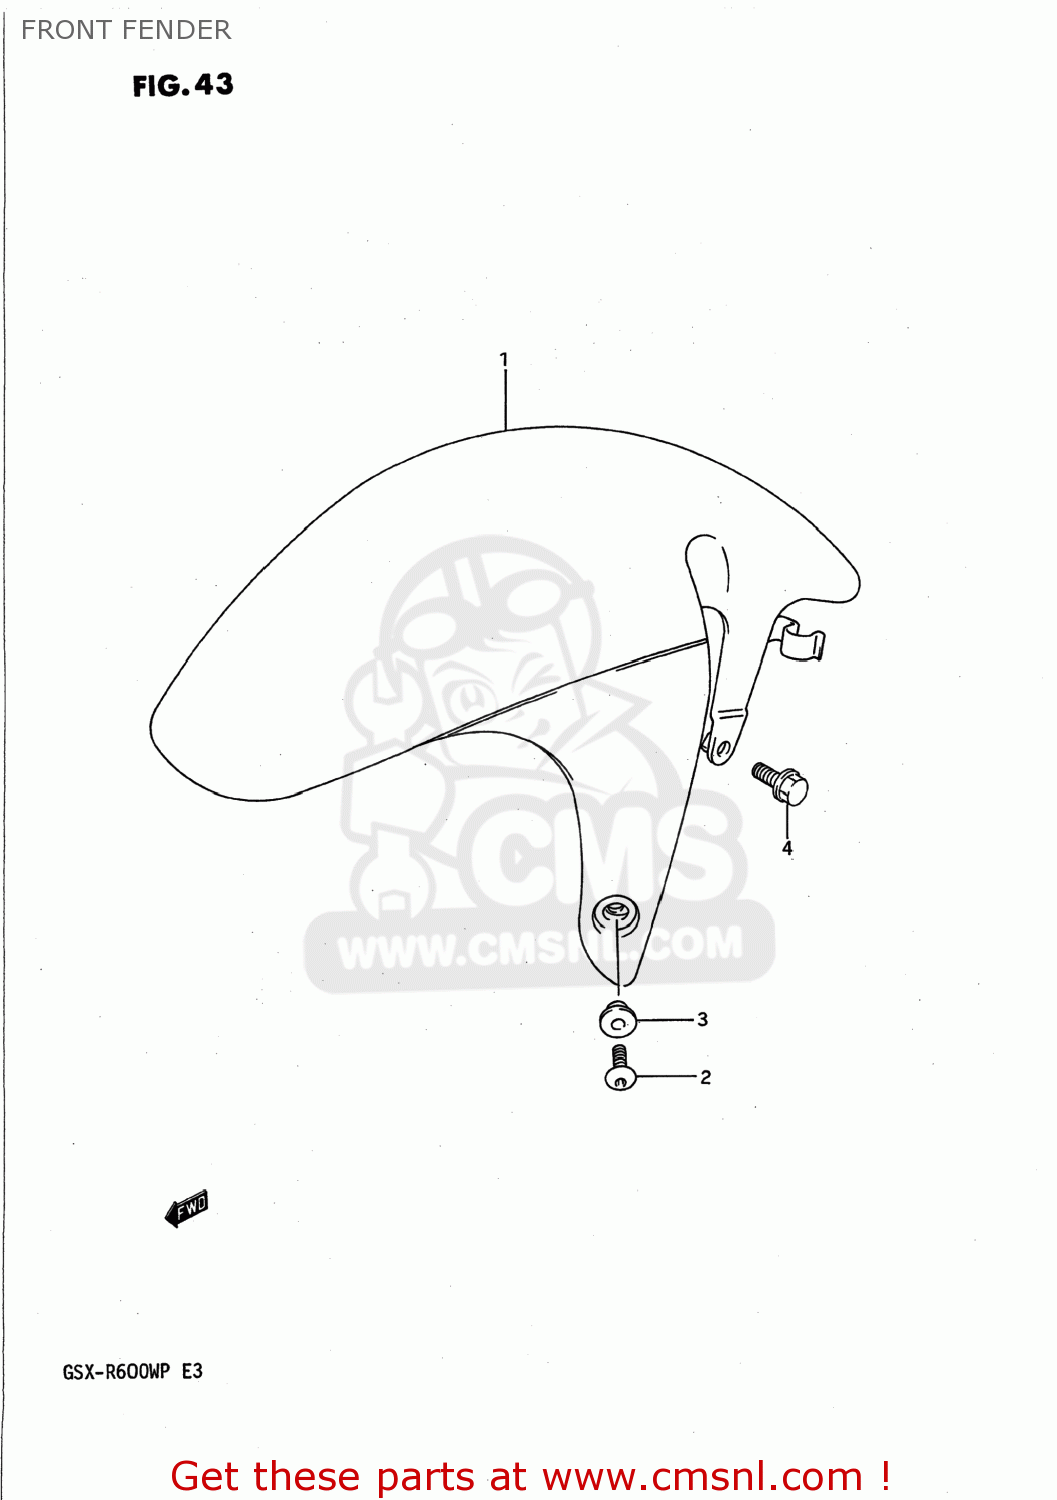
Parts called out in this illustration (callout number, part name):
1	FENDER,FRONT
2	SCREW(6X16)
3	WASHER(6.3X16X1.5)
4	BOLT, LOWER
